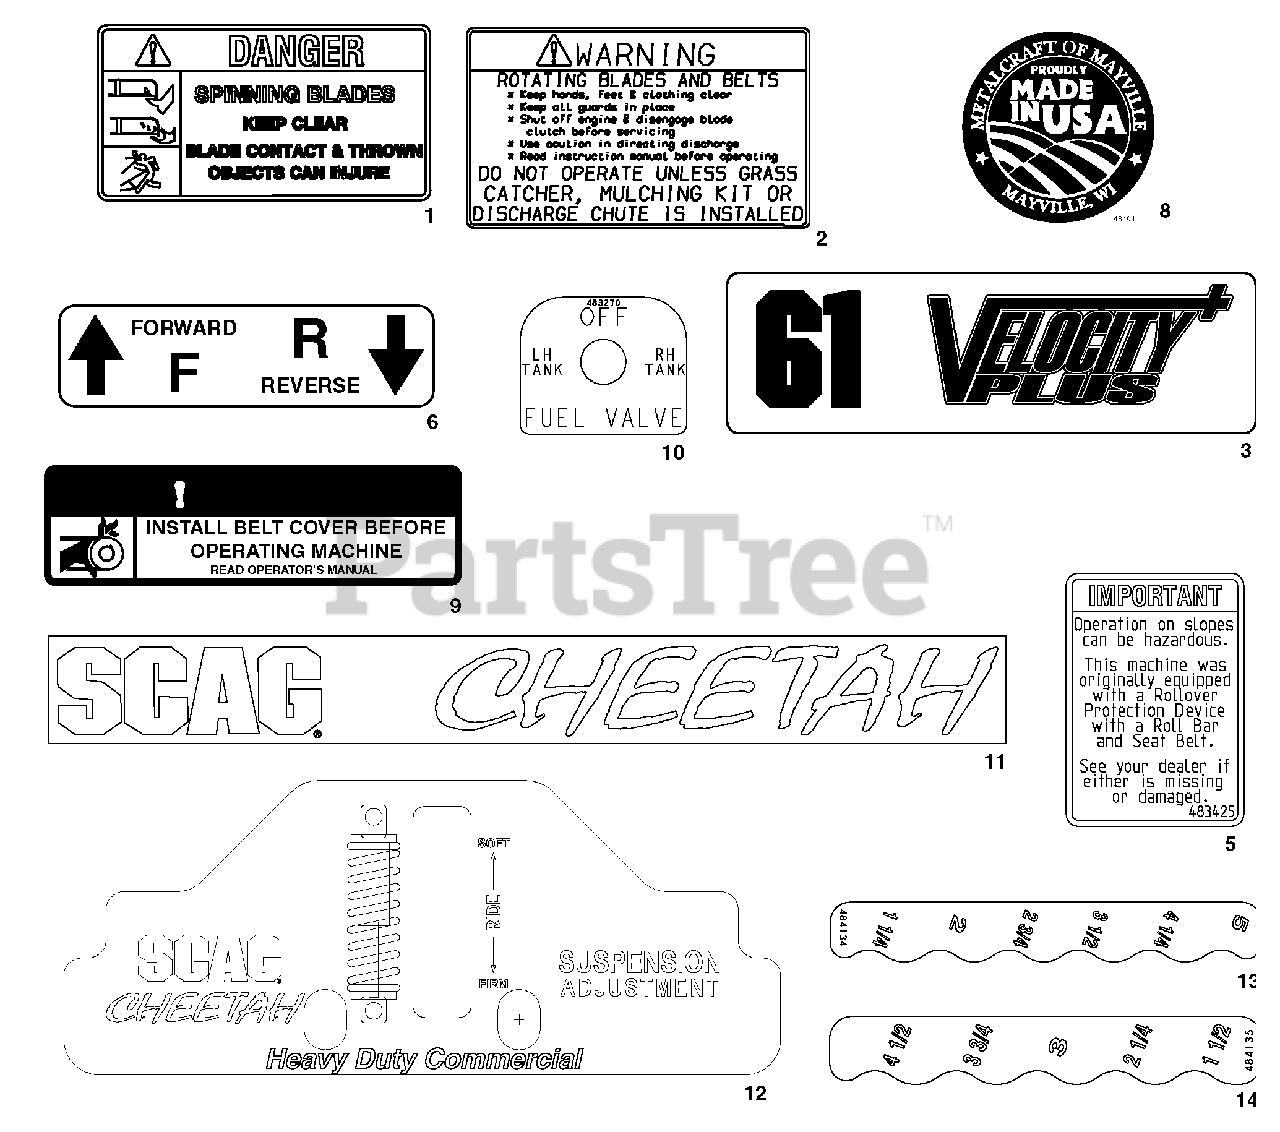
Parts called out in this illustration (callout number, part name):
1	Decal, Spinning Blades
2	Decal, Knives
3	Decal, 61" Velocity Plus
3	Decal, Velocity Plus - 61RD
3	Decal, 72" Velocity Plus
5	Decal, ROPS
6	Decal, Traction Control
8	Decal, Made in USA
9	Decal, Belt Cover
10	Decal, Fuel Shut Off
11	Decal, Scag Cheetah
12	Decal, Suspension Adjustment
13	Decal, Deck Height - LH
14	Decal, Deck Height - RH
